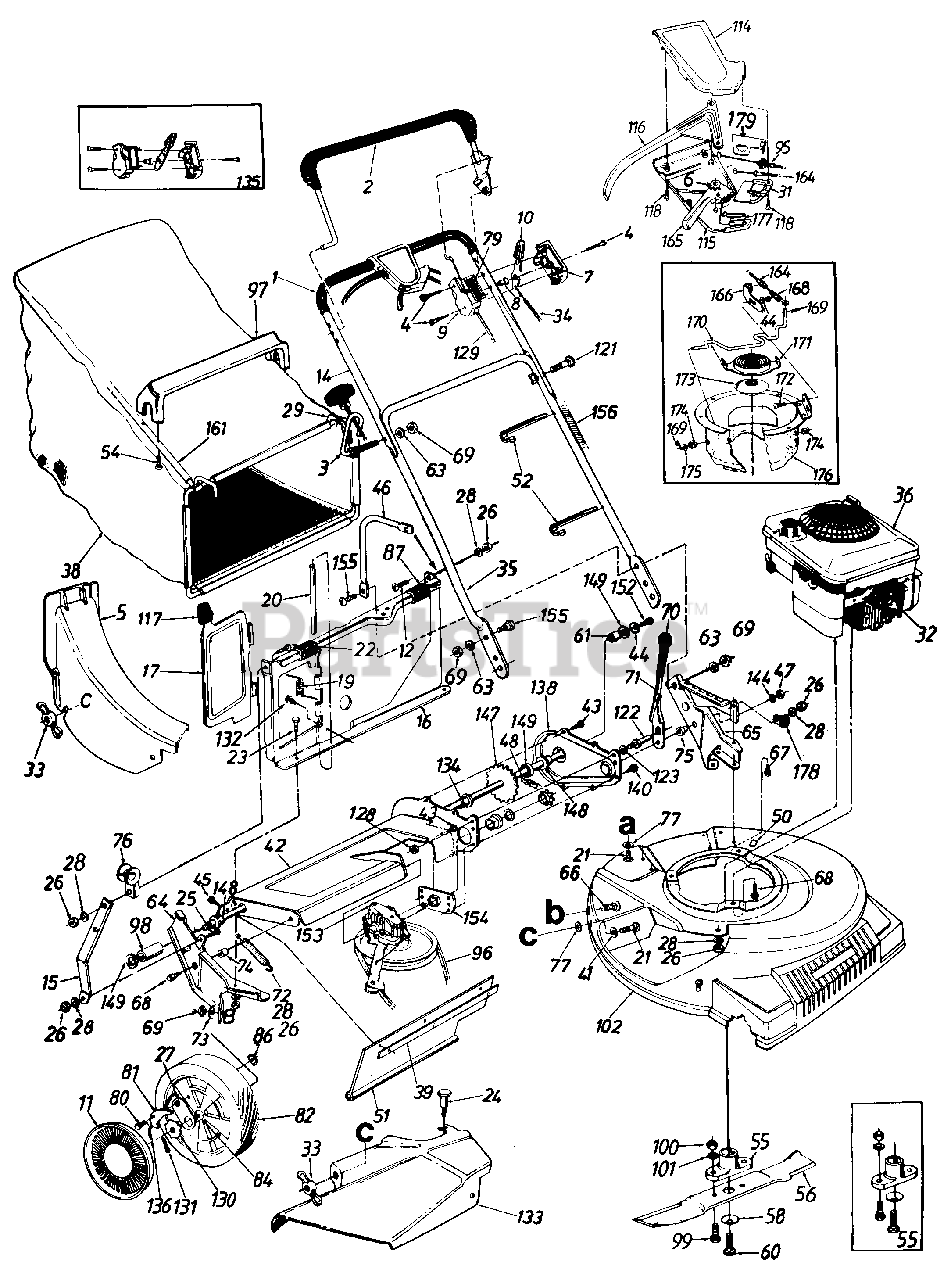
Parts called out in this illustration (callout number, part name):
1	Grip
2	Control Handle Ass'y. L.H.
3	Rope Guide Bolt
4	Truss Mach. Scr. #12 x 1.50" Lg.
5	Rear Discharge Chute Ass'y.
6	3 Tooth Rack Gear Insert
7	Control Panel Half
8	Control Disc Pin
9	Clutch Panel Half
10	Throttle Control Lever
11	Hub Cap
12	Truss Mach. Scr. 1/4-20 x .62" Lg.
14	Upper Handle
19	Torsion Spring
20	Pivot Pin
21	Carriage Bolt 1/4-20 x .62"
22	Truss Mach. Scr. 1/4-20 x .75" Lg.
23	Hex Bolt 1/4-20 x .5" Lg.
24	Shoulder Bolt Special
25	Hex Bolt 1/4-20 x .62" Lg.
26	Hex Nut 1/4-20 Thd.
27	Pawl Plate
28	L-Wash. 1/4 I.D.
31	S.P. Control Cover
32	Spark Plug Insulator
33	Wing Nut
34	Throttle Control Wire 61"
35	Lower Handle
36	Engine
38	Grass Bag
39	Retaining Strip
41	Fl-Wash. .344" I.D. x .62"
44	Bell-Wash. 1/4" I.D.
45	Hex AB-Tap Scr. 1/4 X .62"
46	Part Specification Not Listed
47	Hex Patch L-Nut 3/8-24 Thd.
48	#48 Chain .500" Pitch x 30 Links
51	Rear Flap 3.75" x 17.30" Lg.
52	Cable Tie
54	Hex AB-Tap Scr. #12 x 1.25" Lg.
55	Blade Adapter Kit
56	21" Blade
58	Bell-Wash..46" I.D.
60	Hex Bolt 7/16-20 x 1.5"
61	Spacer.513" I.D.
63	L-Wash. 5/16" I.D.
64	R.H. Handle Wheel Brkt. Ass'y.
65	L.H. Handle Wheel Brkt. Ass'y.
66	Carriage Bolt 5/16-18 x .62"
67	Hex B-Tap Scr. 5/16-18
68	Hex TT-Tap Scr. 3/8-16
69	Hex Nut 5/16-18 Thd.
71	Height Adj. Lever
72	Extension Spring 3.80" Lg.
73	Bell-Wash. 5/16" I.D.
74	Spacer.383" I.D.
75	Shld. Spacer .5" Dia.
76	Rope Guide
77	Bolt Retainer 1/4 x .50" O.D.
79	Control Label
80	Shld. Scr. .342" Dia. x .268
81	Pawl
82	Wheel Ass'y. Comp. Rear
84	Sleeve Bearing 1/2" I.D.
86	Flat Nut 1/4-20 Thd.
87	Panel Clip
95	S.P. Cable 50" Lg.
96	"V"-Belt
97	Bag Handle
98	Sleeve.526" I.D.
99	Hex Bolt 3/8-24 x 1.0" Lg.
100	Hex Nut 3/8-24 Thd.
101	L-Wash. 3/8" I.D.
115	Self-Propelled Control Cover
116	Control Lever
117	Door Grip
118	Fl-"C"-Sunk Hd. Tap Scr. #10 x .75" Lg.
121	Curved Carr. Bolt 5/16-18 x 1.38" Lg.
122	Shld. Pin 1.43" Lg.
123	L-Wash. 3/8" I.D.
128	Hex Jam Nut 3/8-24 Thd.
129	Control Cable 46"
130	Ratchet Wheel 1.62" O.D.
131	Cotter Pin 1/8" Dia. x 1"
132	Hex B-Tap Scr. #10 x .38" Lg.
133	Side Chute Deflector Ass'y.
134	Hex Flange Bearing
135	Kit Control Housing Comp.
136	Spring Nylon
144	Fl-Wash. .385" I.D. x .37"
147	Rear Shaft Ass'y. 21.94" Lg .
148	Hex Flange Brg. .506" I.D.
149	Fl-Wash. .531" I.D. x.930"
152	Hex Bolt 1/4-20 x .62" Lg. (Grade 5)
153	Transmission Comp.
155	Truss Mach. Scr. 5/16-18 x .75" Lg.
156	Plastic Tubing
161	Part Specification Not Listed
164	Spd. Control Cable 50" Lg.
165	6-Spd. Shift Lever
169	Cot-Pin 3/32" Dia. x .75" Lg.
170	Shift Rod
171	Movable Pulley Half Ass'y.
172	Carr. Bolt 1/4-20 X .5" Lg.
173	Splined Pulley Half
174	Flanged Bushing
175	Fl-Wash. .328" I.D. x .68" O.D.
176	Cable Mtg. Brkt. Ass'y.
177	Shift Lever Spring
178	Clamp
179	6-Speed Cable Brkt.
